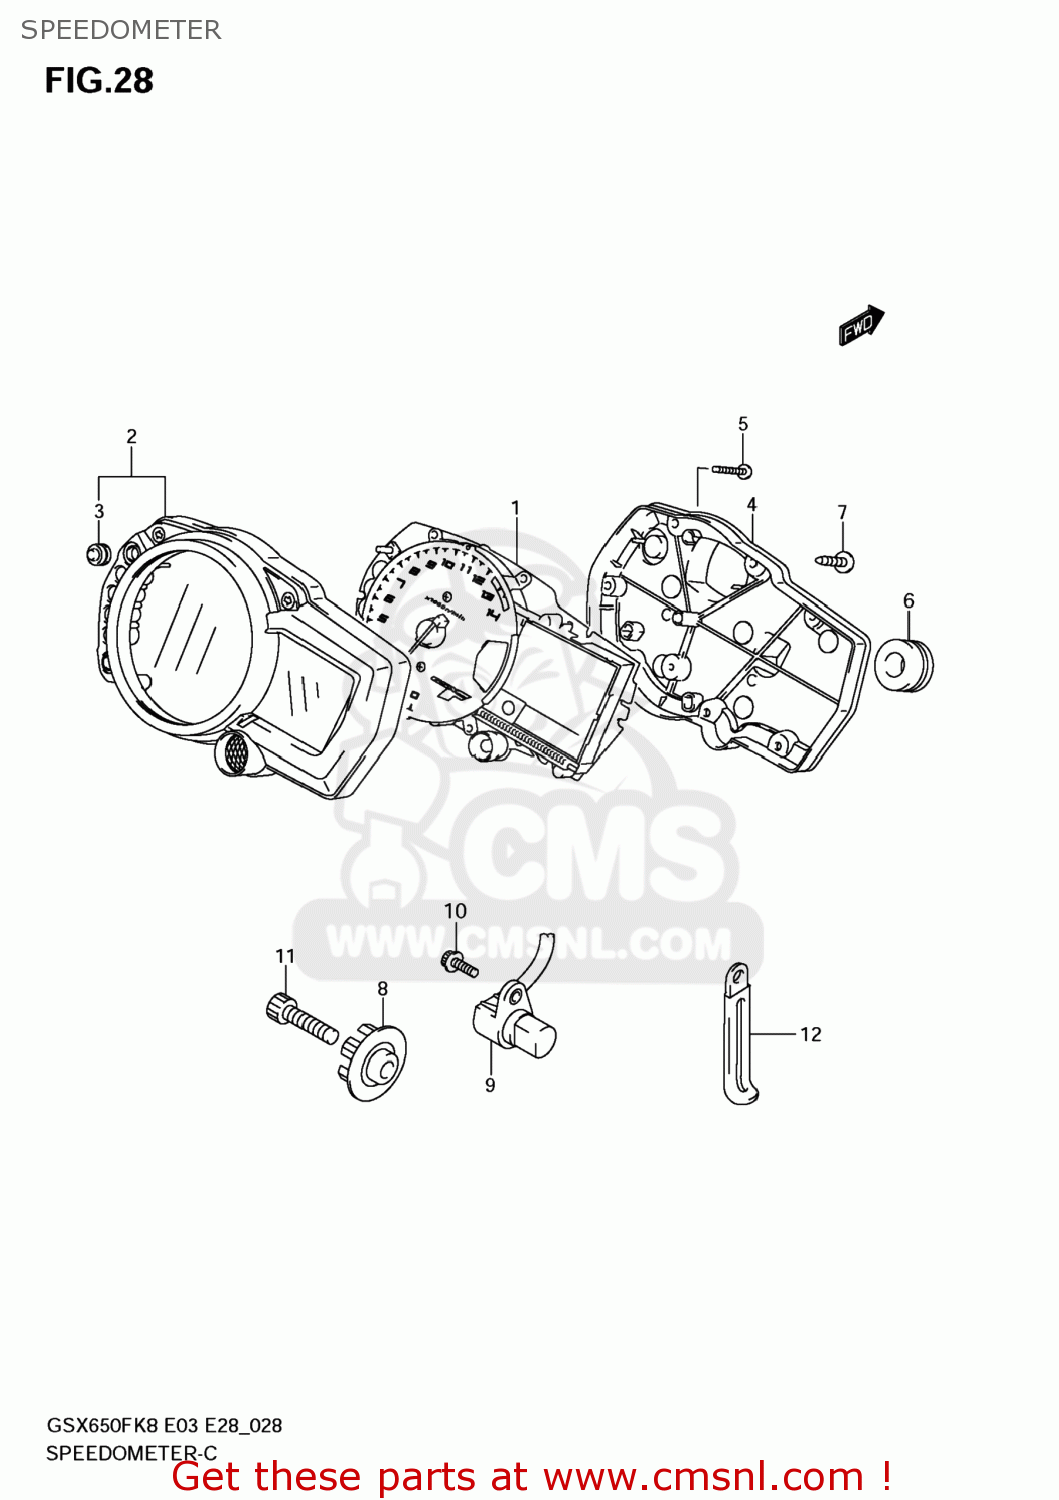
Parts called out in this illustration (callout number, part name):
1	SPEED & TACHOMETER ASSY
2	CASE,UPR
3	RUBBER,SWITCH
4	CASE,LWR
5	SCREW(3X16)
6	CUSHION
7	SCREW
8	ROTOR,SPEED
9	SENSOR,SPEED
10	BOLT
11	BOLT
12	CLAMP(L:45)
